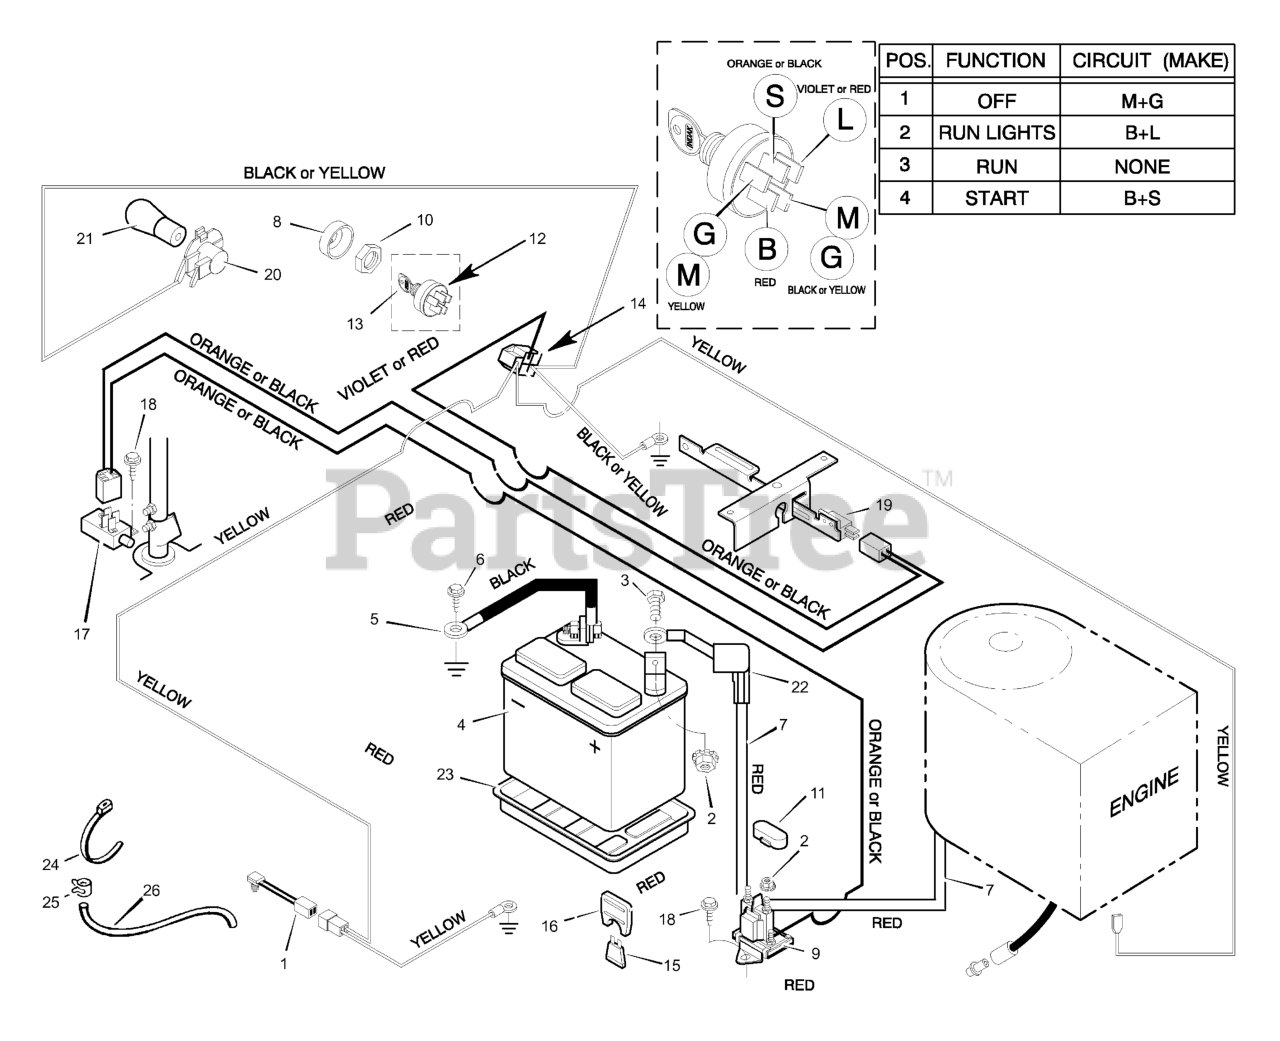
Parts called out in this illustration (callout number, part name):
1	Switch, Seat Sensor
2	Locknut
4	Battery
5	Cable, Battery Ground
7	Cable, Red Battery
8	Cap, Ignition
9	Solenoid
10	Nut, Hex
11	Cover, Solenoid
12	Switch, Ignition
13	Key, Ignition
14	Harness, Chassis Wire
16	Holder, Fuse
17	Switch, Limit
19	Switch, Limit
20	Socket, Light
21	Bulb, Light
22	Cover, Terminal
23	Tray, Battery
26	Tube, Drain
